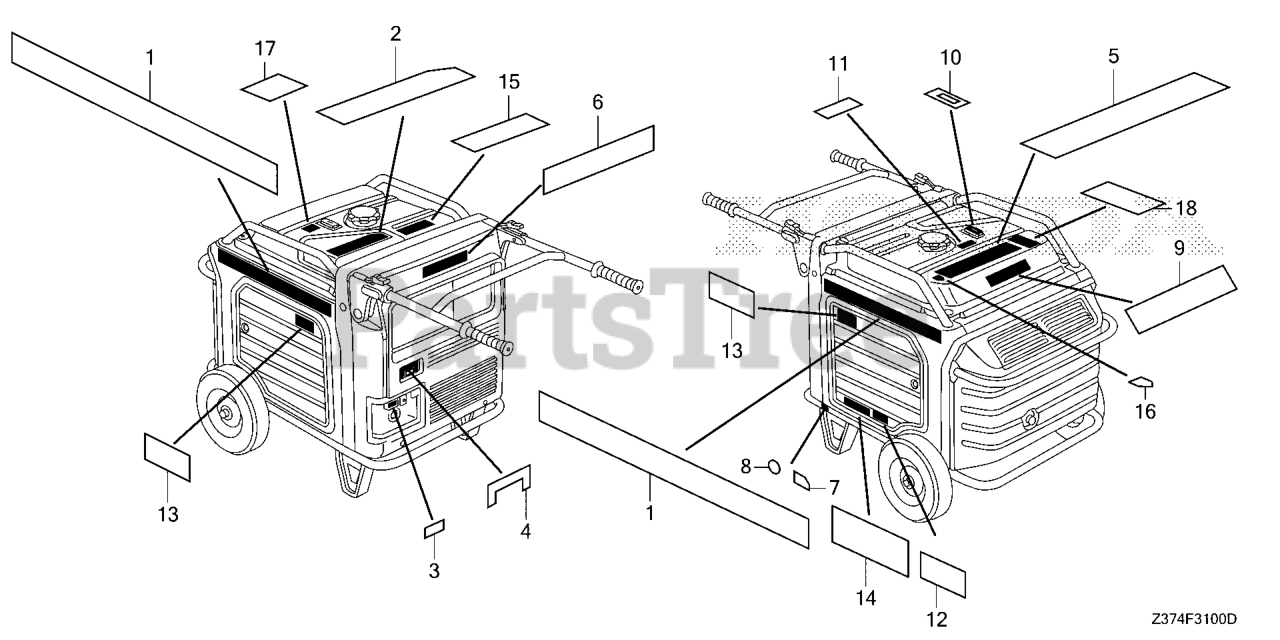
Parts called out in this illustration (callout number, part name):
1	MARK, EMBLEM
2	MARK, PUMP COVER
3	MARK, BRANCH FUSE (ENGLISH)
4	MARK, PANEL SWITCH
5	LABEL, OPERATOR WARNING (AG)
6	MARK, HONDA
8	MARK, GROUND
9	LABEL, EX. WARNING (E)
10	MARK, FUEL INDICATION
11	LABEL, FUEL
12	MARK, OIL CAUTION
14	MARK, SPEC
15	LABEL, FUEL WARNING (ENGLISH)
16	MARK, DIRECTION (AG)
17	LABEL, SHUTOFF CAUTION
18	LABEL, WARNING
